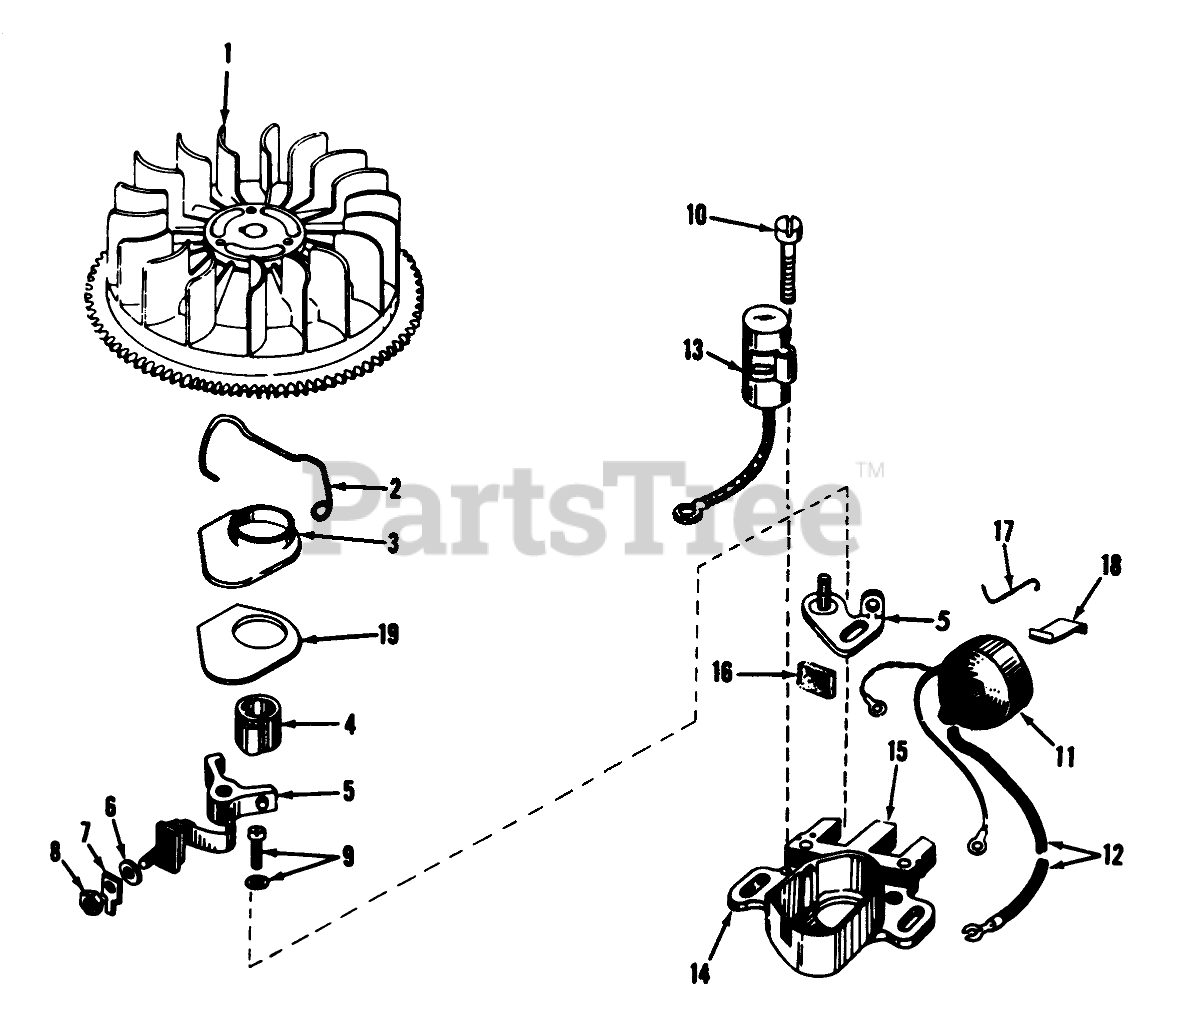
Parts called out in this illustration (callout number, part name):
1	Flywheel
2	Spring Breaker Box
3	Cover, Dust
4	Cam-Breaker
5	Breaker Assy.
6	Washer
7	Terminal, Ground
8	DECAL
9	Breaker Screw
10	Condenser Screw
11	Coil Assy., (Incl. #12)
12	Wire, Lead
13	Condenser
14	Core & Plate
15	Stator Assembly, (Incl. #2, 3, 5 thru 14 & 16 thru 19)
16	Felt,Cam Wiper
17	Clip, Coil
18	Spring Coil Wedge
19	Gasket, Dust Cover
